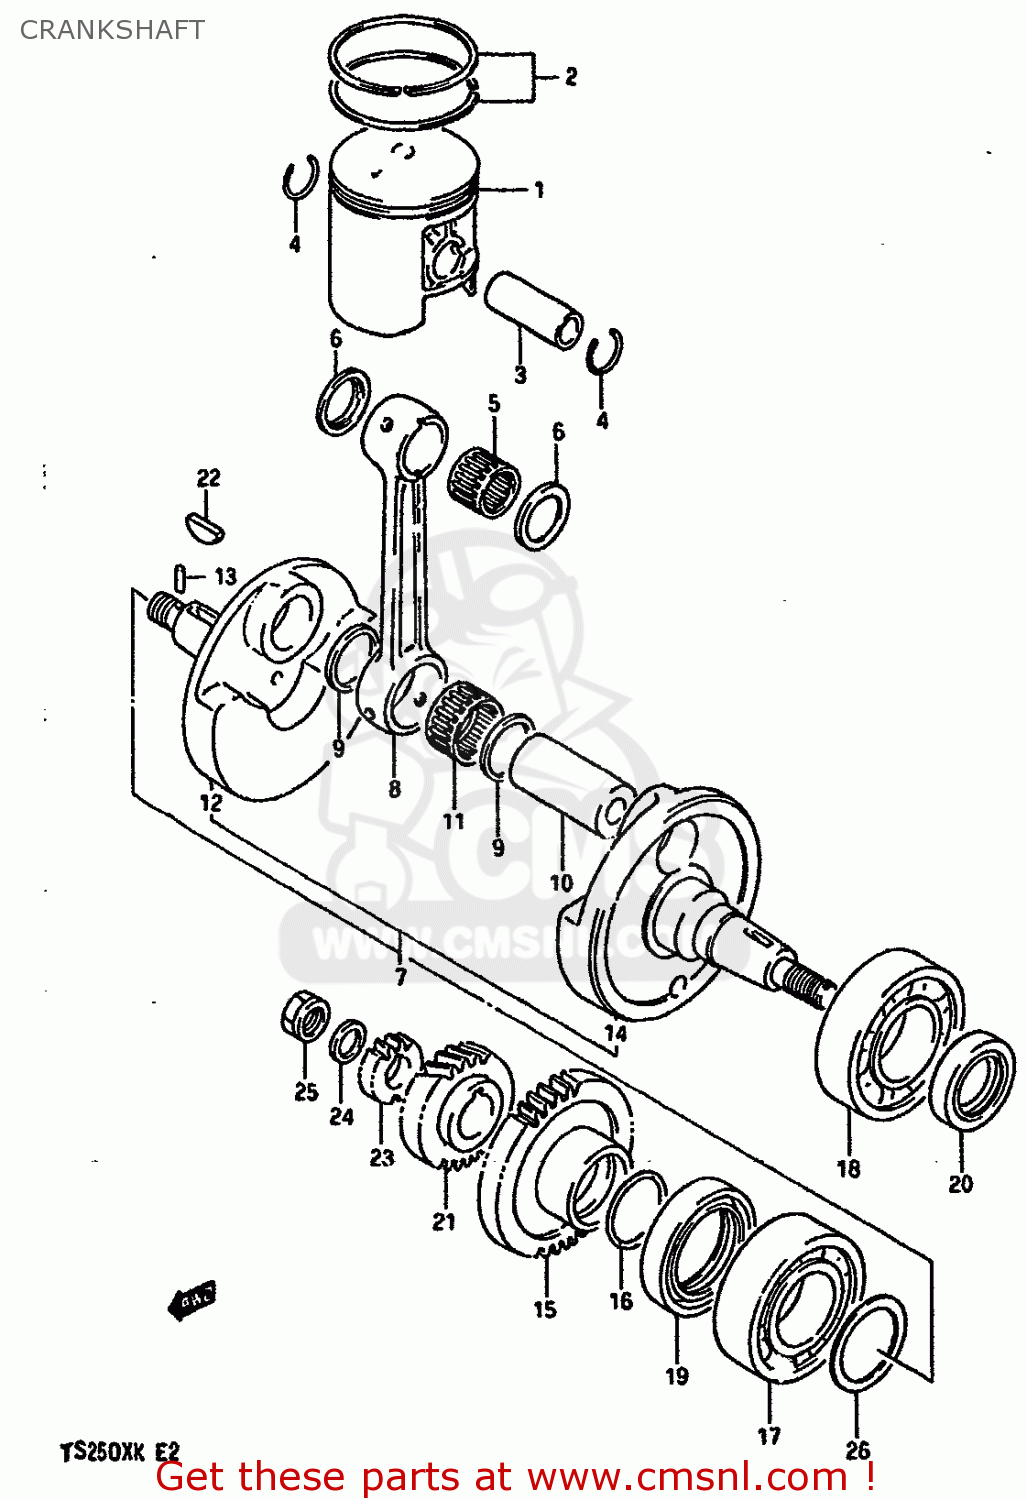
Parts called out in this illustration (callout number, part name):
1	PISTON (OS:1.0)
2	RING SET,PISTON
3	PIN,PISTON (18MM)
4	CIRCLIP,PISTON PIN
5	BEARING(18X23X24)
6	WASHER
7	CRANKSHAFT ASSY
8	CONNECTING ROD
9	WASHER(26X32X1.5)
10	PIN,CRANK
11	BEARING(26X32X17)
12	CRANKSHAFT,RH
13	PIN 3X5
14	CRANKSHAFT,LH
15	GEAR,CRANK BALANCER DRIVE
16	O RING(D:2.4,ID:27.7)
17	BALL BEARING 30X62X16
18	BEARING(32X65X17)
19	SEAL,OIL(36X52X8)
20	SEAL,OIL(25X38X7)
21	GEAR,PRIMARY DRIVE
22	KEY
23	GEAR,WATER PUMP DRIVE
24	WASHER
25	NUT
26	SHIM(30X40X0.65)
